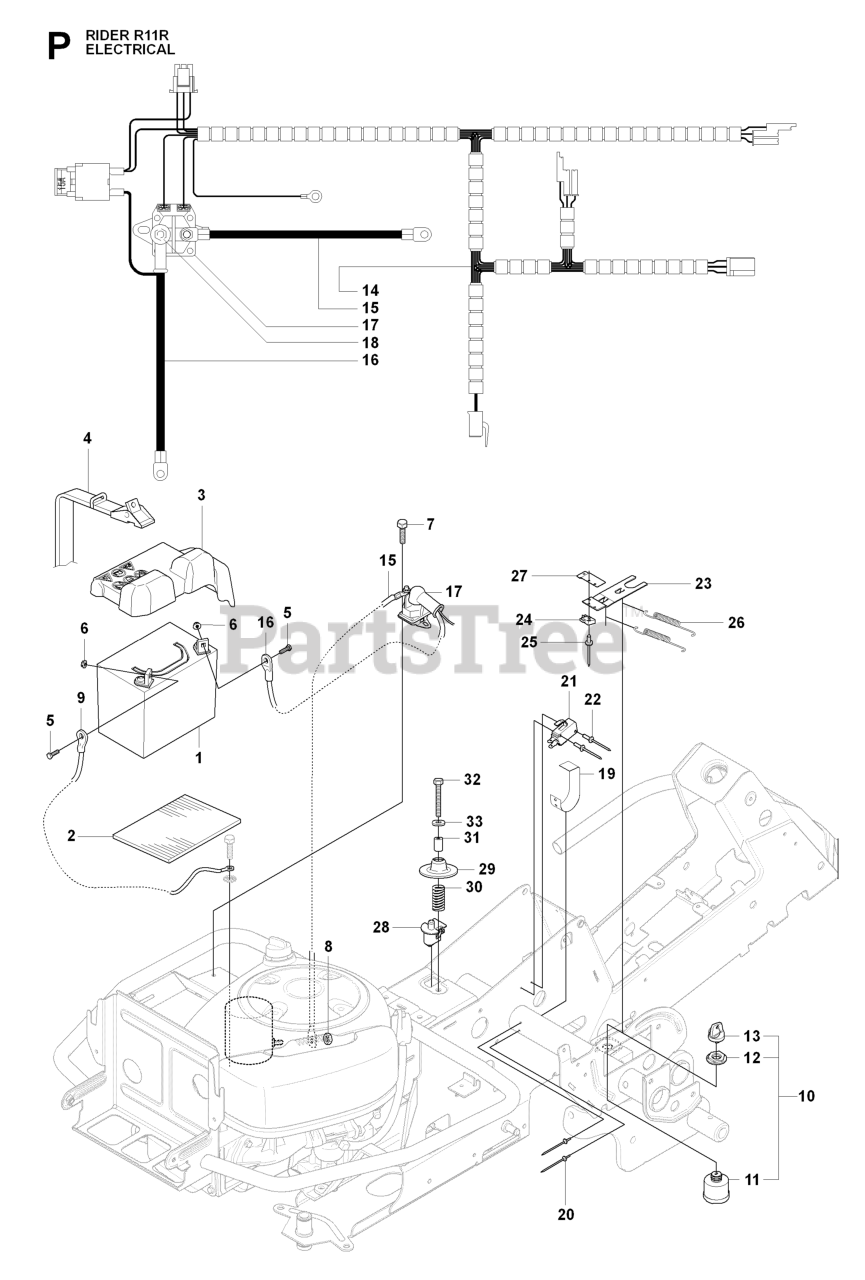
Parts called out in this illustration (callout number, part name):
5	SCREW EHHM
10	IGNITION SWITCH
11	IGNITION SWITCH
13	IGNITION KEY
21	%BRAKER
24	%BRAKER
31	SPACER TUBE
32	SCREW
33	WASHER BRB 8.4X17
